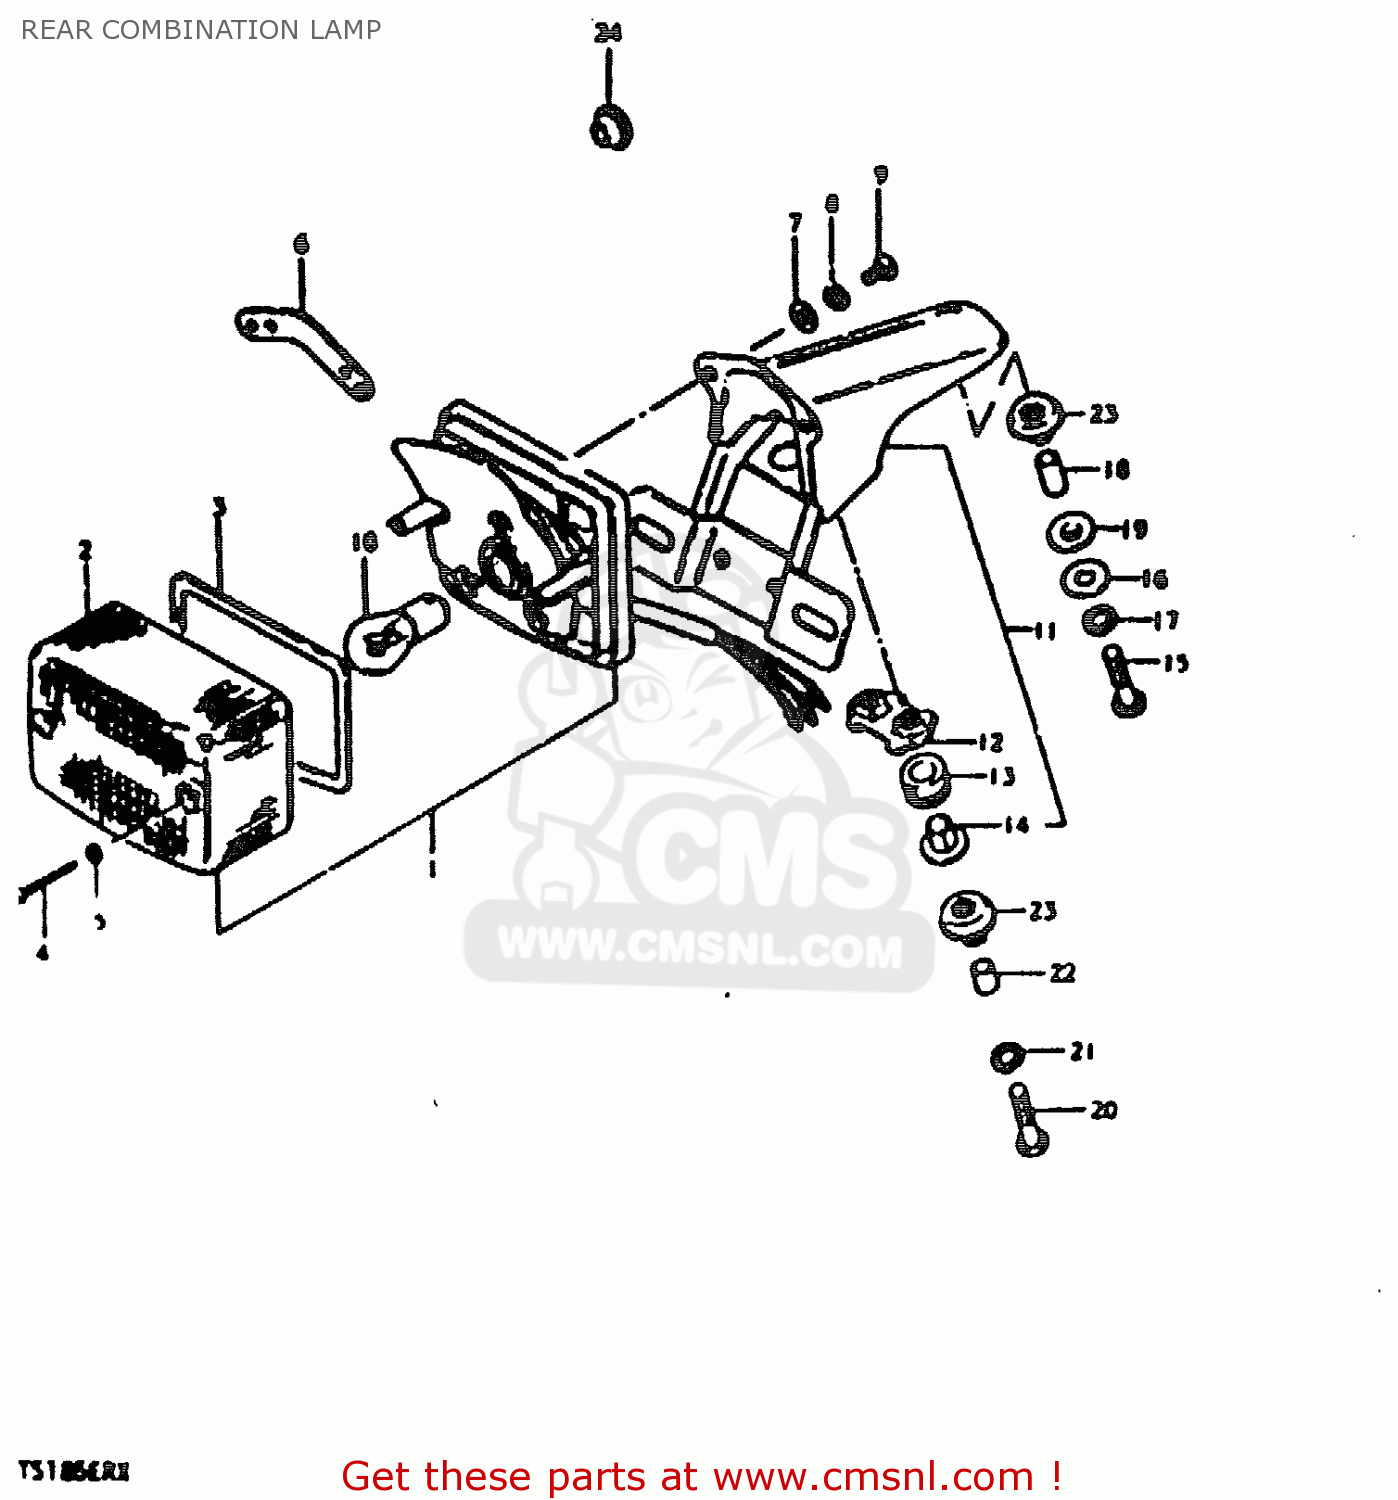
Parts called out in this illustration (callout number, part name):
1	LAMP UNIT,REAR COMBINATION
2	LENS
3	GASKET (NAS)
4	BOLT
5	GASKET (NAS)
6	PLATE,REAR COMBINATION LAMP
7	WASHER
8	LOCK WASHER
9	SCREW
10	BULB(6V32/3CP,STANLEY)
11	BRACKET UNIT,TAIL LAMP
12	PLATE
13	CUSHION
14	SPACER
15	BOLT
16	WASHER (6.5X20X1.2)
17	LOCK WASHER
18	SPACER
19	CUSHION
20	BOLT 6X40
21	LOCK WASHER
22	SPACER (6.8X10X11.5)
23	CUSHION
24	GROMMET
